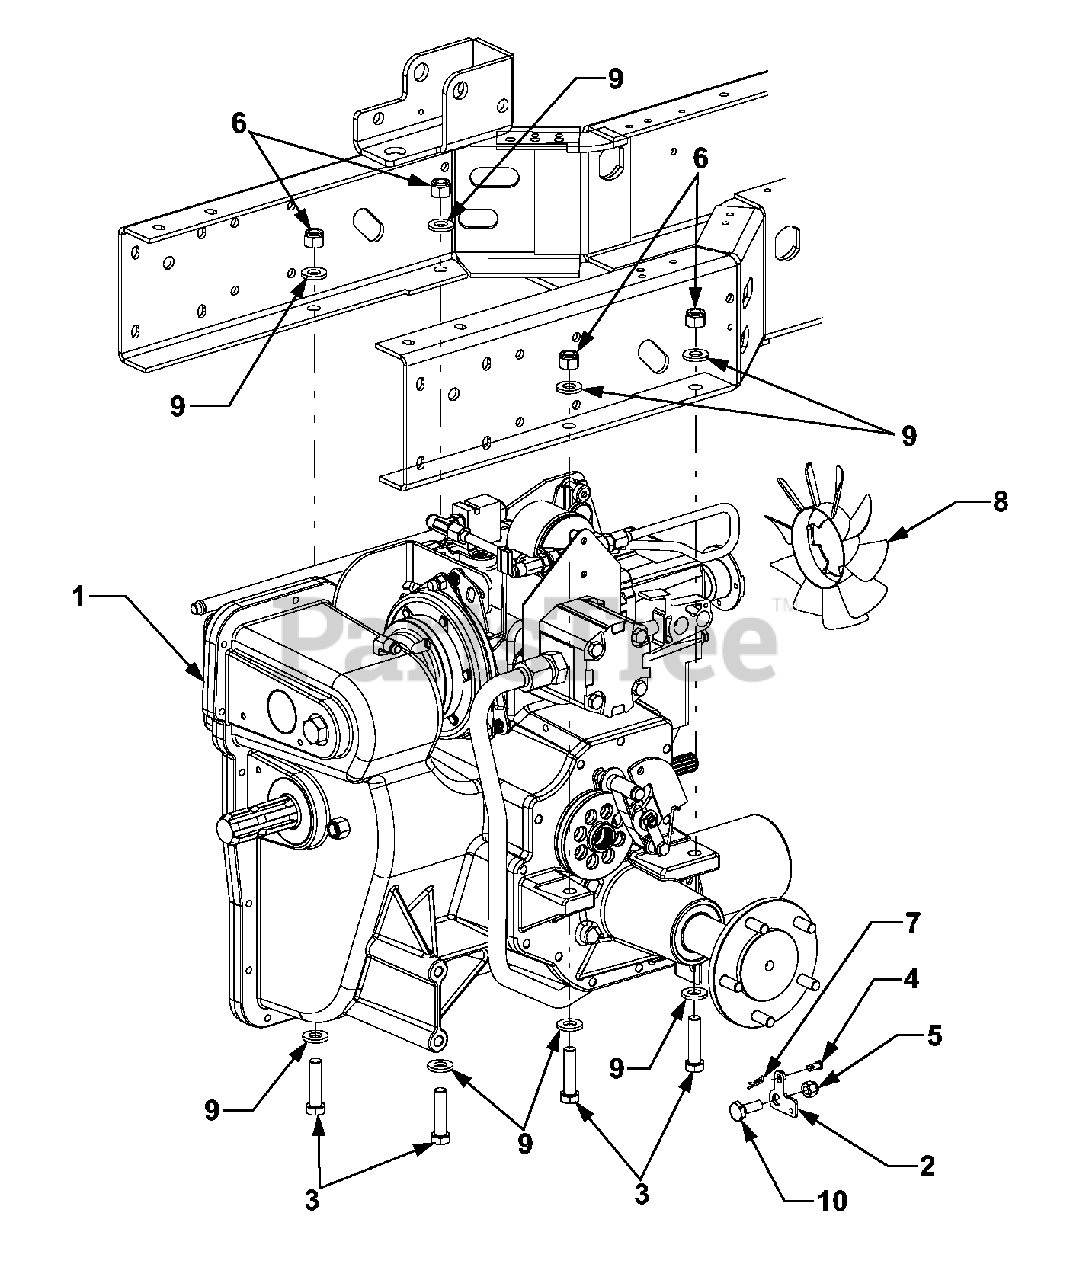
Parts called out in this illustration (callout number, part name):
1	Transmission Assembly
2	Link, Diff Lock Actuator
3	Screw, Hex Cap 1/2-13 x 2.0 GR8
4	Pin, Clevis, .25 x .50
5	Nut. Hex Insert Lock, 3/8-24
6	Nut, Hex Insert Lock, 1/2-13
7	Pin, Internal Cotter
8	Fan, Transmission Cooling
9	Washer, Flat, .531 x .1062 x .134
10	Screw, Shoulder, 1/2 Dia. x .180
